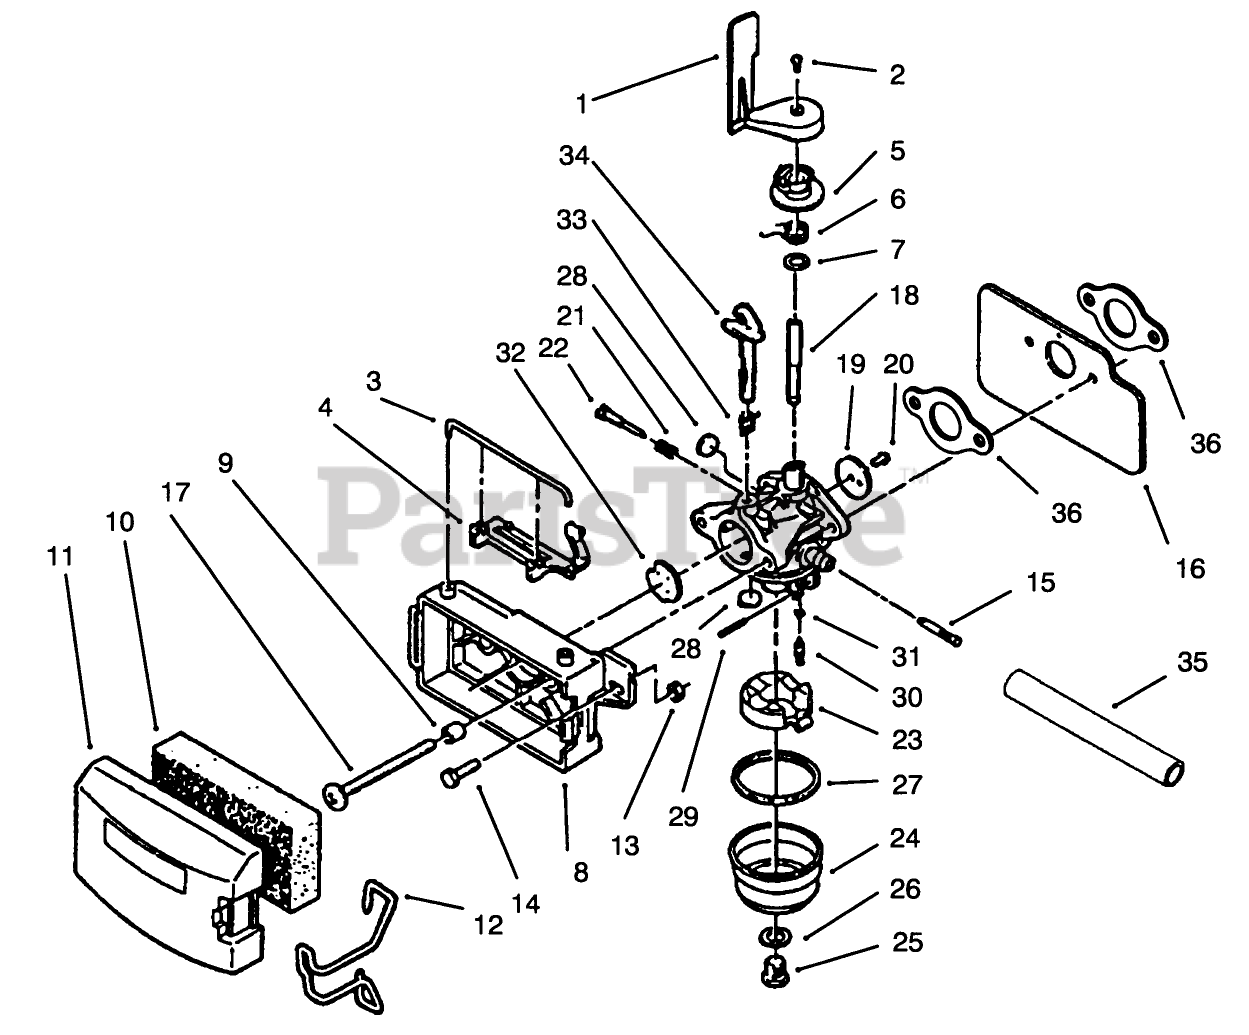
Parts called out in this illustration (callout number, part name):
1	AIR VANE F
2	SCREW,PAN HD F
3	RETAINER
5	COLLAR A/VAVE F
6	THROTTLE SPR E
7	WASHER VF
12	RETAINER-COVER, FILTER
15	SCREEN FUEL PITTS
18	Throttle Shaft
19	Throttle Valve
20	Screw-Throttle Valve
21	Spring-Idle Needle
22	Idle Needle
24	Fuel Bowl
25	Screw-Bowl Retainer
26	Bowl Retainer Gasket
27	Fuel Bowl Gasket
28	Plug-Welch
29	Float Shaft
30	Inlet Needle Valve
31	Valve Seat
32	Choke Valve
33	Choke Return Spring
34	Choke Shaft
35	GAS LINE
36	GASKET CARB S
